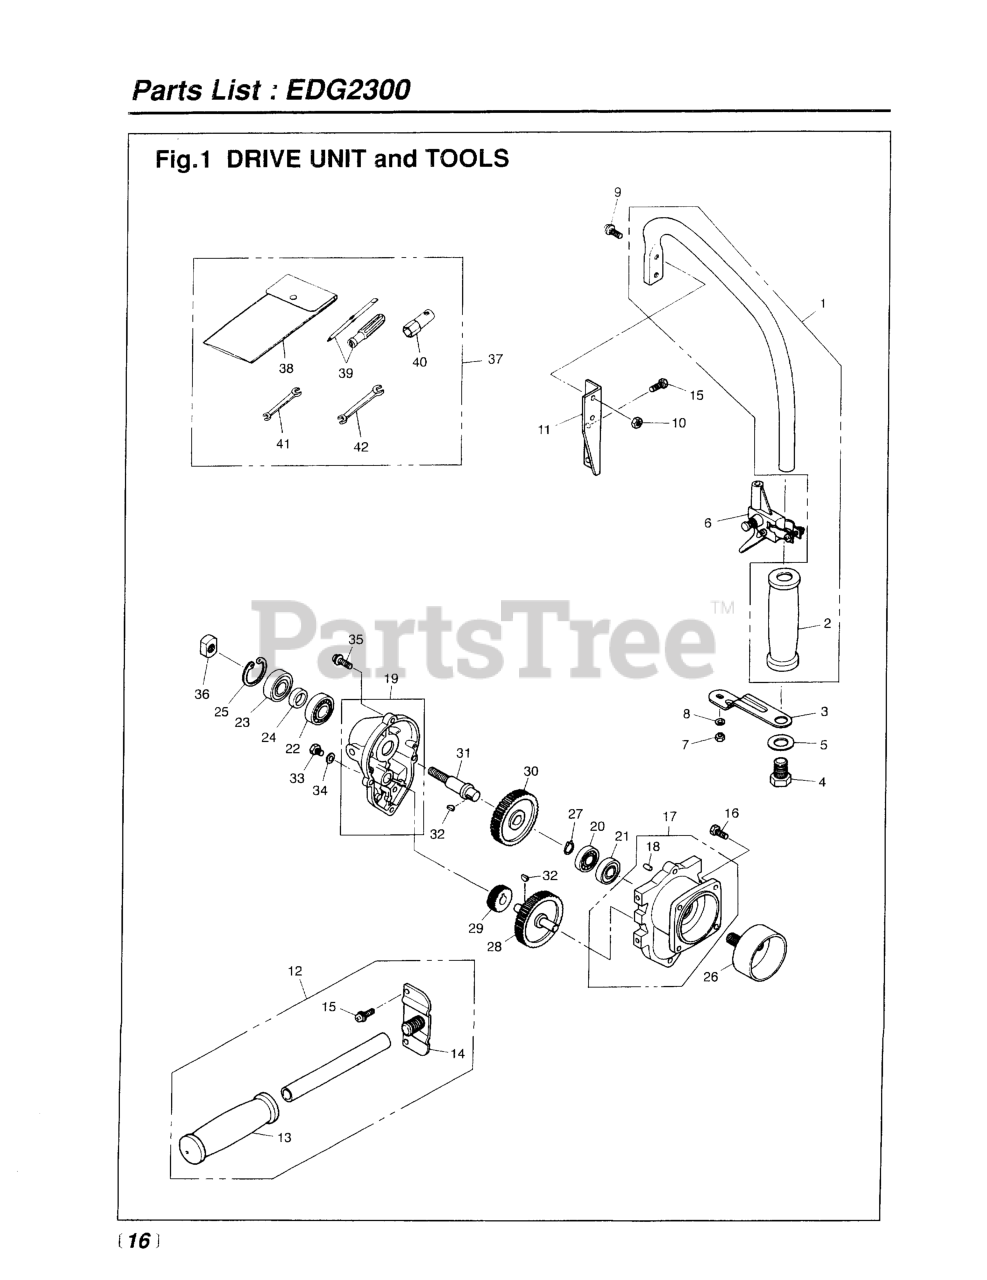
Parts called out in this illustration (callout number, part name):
1	HANDLE, RIGHT
3	STAY
5	WASHER, M14 x 2.3
6	LEVER, THROTTLE
7	NUT (M5X0.8)
8	WASHER, SPRING M4 x 1.3
9	SCREW, M5 x 16
10	NUT, M5 X 4
11	BRACKET, RIGHT
12	HANDLE, LEFT COMP
13	GRIP (REPLACES -14220)
14	BRACKET, LEFT
15	BOLT, M6 x 16
18	PIN, DOWEL
19	CASE (USE -11201)
20	BEARING
25	RING, SNAP, M35 X 1.5
26	DRUM, CLUTCH
27	RING, SNAP (RPLS 3130-13270)
28	GEAR, DRIVE(USE 13101)
29	GEAR, IDLER
30	GEAR, DRIVEN
31	SHAFT, PTO
32	KEY
34	WASHER, M6 X .8
35	BOLT M5 x 20 (RPLS -12280)
37	TOOL SET
39	SCREWDRIVER
40	SOCKET, HEX, 3/4
41	SPANNER, 8 X 10 (RPLS 2540- )
42	WRENCH (TOOL)
